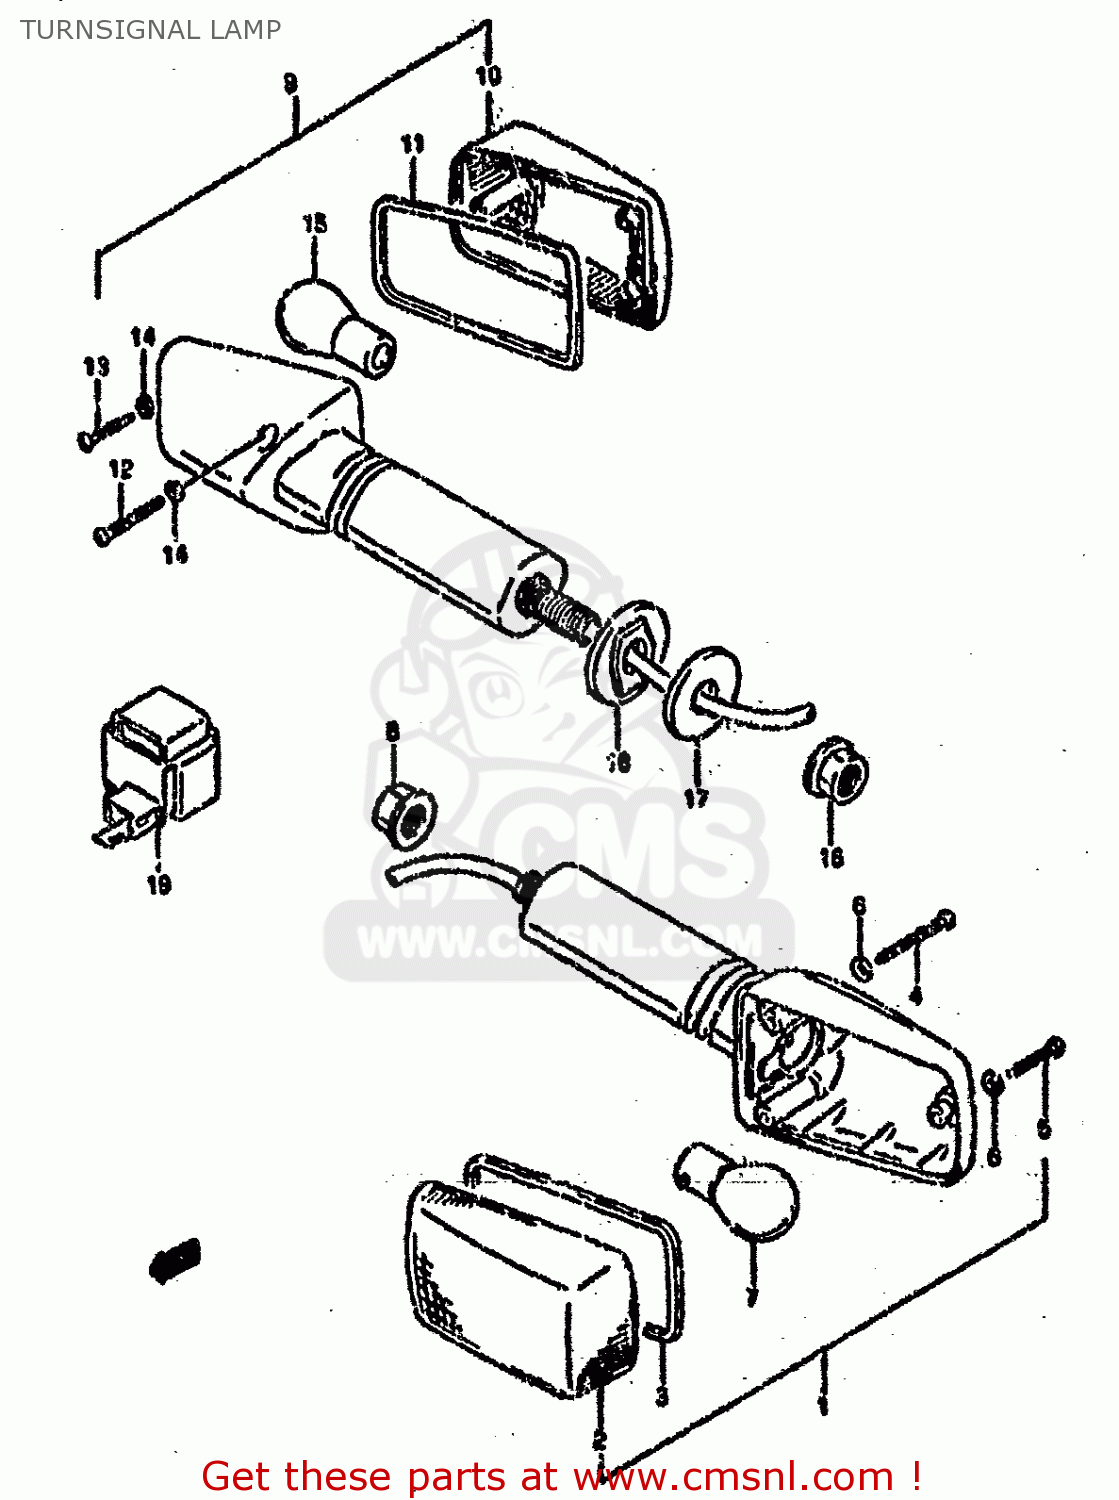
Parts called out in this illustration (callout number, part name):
1	LAMP ASSEMBLY,FRONT TURN SIGNAL
2	LENS
3	GASKET (NAS)
4	SCREW(3X30)
5	SCREW
6	GASKET (NAS)
7	BULB(12V21W)
8	NUT
9	LAMP ASSY,RR TURNSIGNAL
10	LENS
11	GASKET (NAS)
12	SCREW(3X30)
13	SCREW
14	GASKET (NAS)
15	BULB(12V21W)
16	NUT
17	WASHER(10.5X30X2.3)
18	SPACER,RR TURNSIGNAL
19	RELAY ASSY,TURNSIGNAL LAMP
